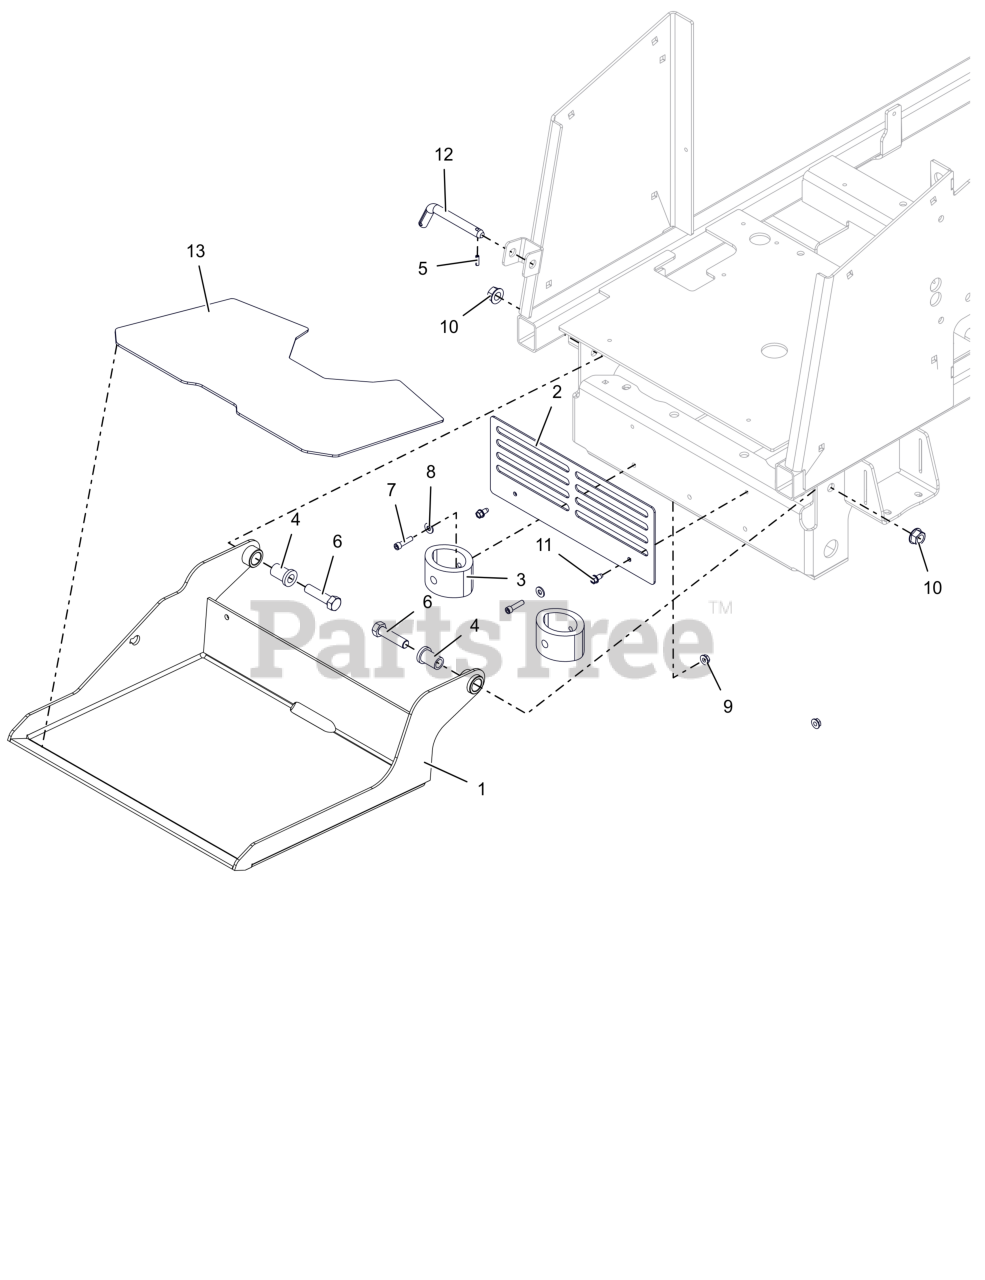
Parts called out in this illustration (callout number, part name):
1	WLDMT, OPERATOR PLATFORM - 48-52" (BLACK)
2	GUARD- FOOT - 48/52"
3	BUMPER, PLATFORM
4	BSHG-FLG .515X.746X1.290X1.000
5	PIN-ROLL .188X.63
6	BLT, HEX .50-13X2.00 G5 ZCC
7	SCR, SKH .25-20X1.00
8	WSHR,FLT .281X.625X.065 ZCC
9	NUT-LK-CTR-FLG .25-20 ZC120
10	NUT-LK-CTR-FLG .500-13 GG ZCC
11	SCR-TAP .25-20X.50 HWH ZCC
12	PIN, HOC SELECTOR/PLTFRM LOCK
13	TAPE, OPERATOR PLATFORM GRIP
